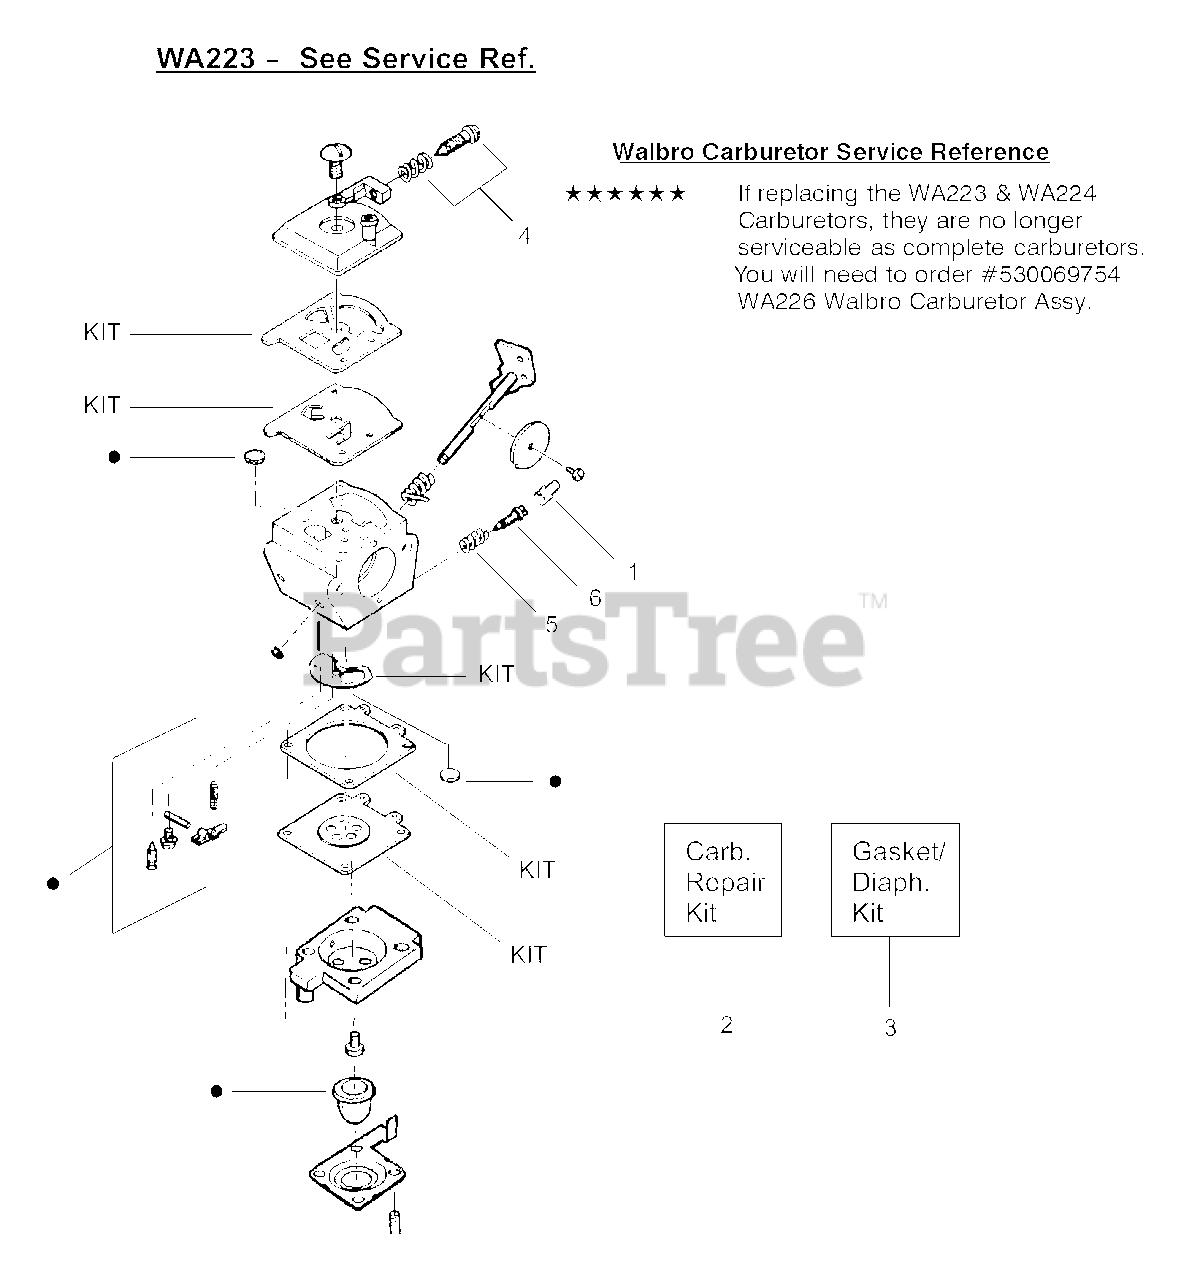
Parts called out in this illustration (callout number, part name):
1	Limiter Cap
2	Carburetor WA223
2	Carburetor WA224
2	Carburetor WA226
2	Carburetor C1U-W7
3	Gasket/Diaphragm WA223, WA224 & WA226
3	Gasket/Diaphragm C1U-W7 (Zama)
4	Idle Screw & Spring Kit
5	Low Speed Spring
6	Low Speed Needle
530069754	Carburetor Assembly (WA226)
